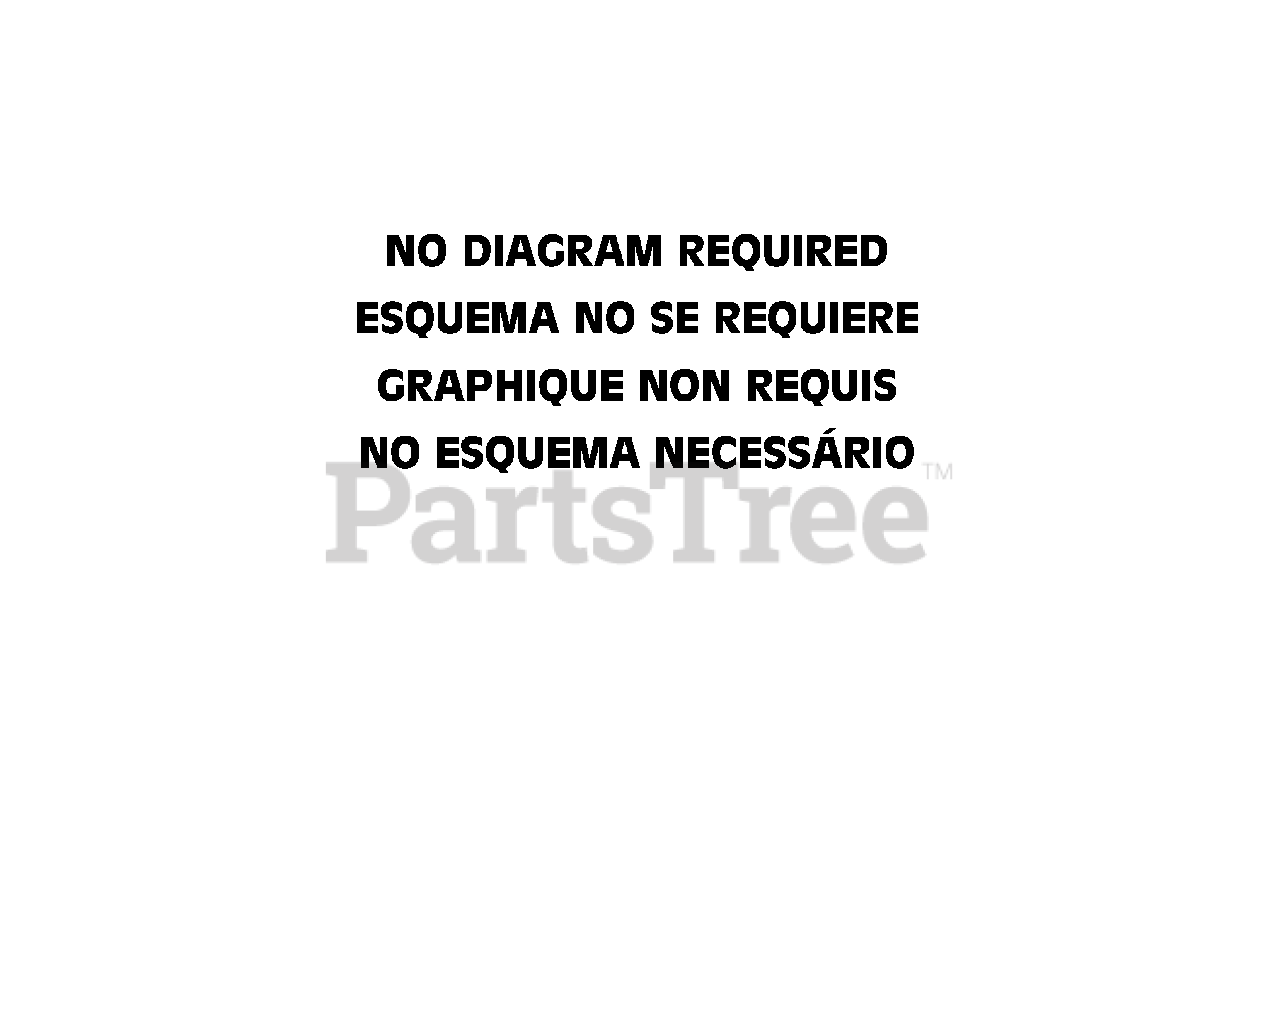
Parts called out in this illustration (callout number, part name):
1	CAP/VENT KIT - REPOWER
2	CAP
3	GASKET, CAP
5	REPOWER FILTRATION KIT
6	FILTER, AIR - HEAVY DUTY
7	FILTER, FUEL
8	TUNE-UP KIT
9	FILTER, AIR - HEAVY DUTY
10	FILTER, FUEL
12	GASKET KIT
13	GASKET, CRANKCASE
14	GASKET, CYLINDER
15	GASKET, INTAKE
16	GASKET, INTAKE
17	GASKET, EXHAUST
18	SHIELD, EXHAUST
